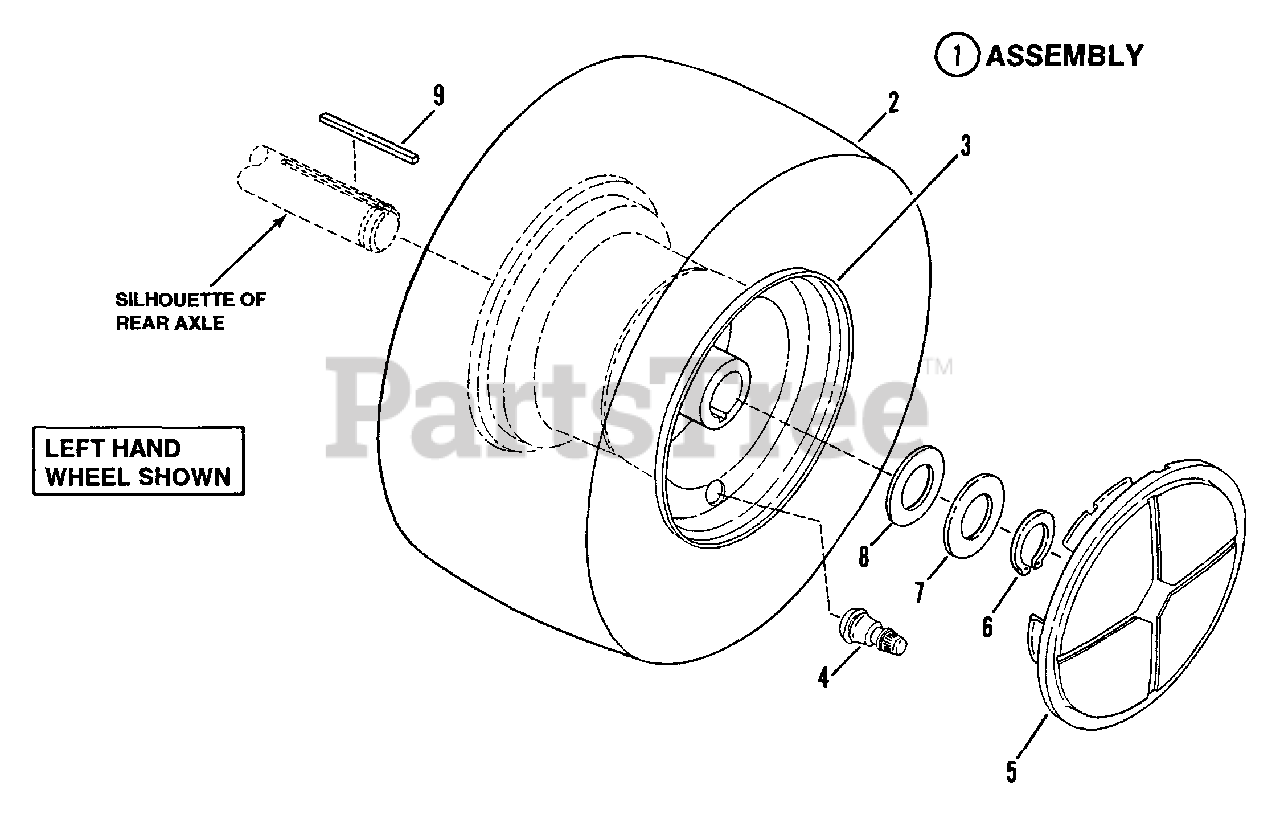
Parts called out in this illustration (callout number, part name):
1	ASSEMBLY, Rear Tire & Rim
2	TIRE, 20 x 10
3	RIM, 8.00 x 7.00
4	VALVE, Air (Snap-in)
5	WHEEL-COVER
6	RING, Retaining
7	WASHER, 49/64" I.D. x 1 5/8" O.D. Thrust
8	WASHER, Flat 49/64" I.D. X 1 1/2" O.D.
9	KEY, Square, 3/16" x 2 1/2"
